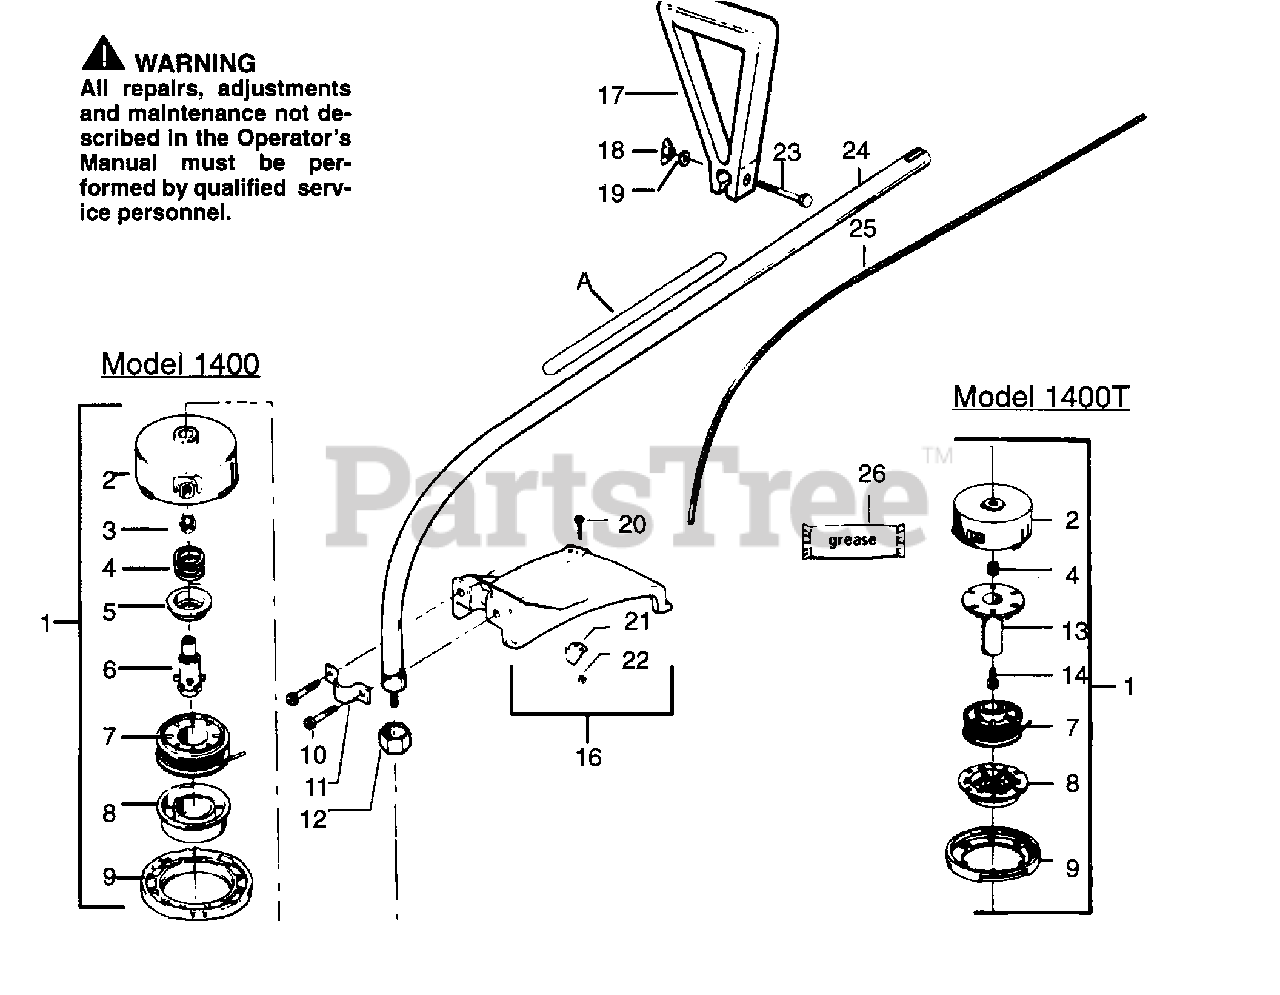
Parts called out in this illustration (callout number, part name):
1	Cutting Head Ass'y.-See Service Ref. 3
2	Model 1400 G.TRIMMER
2	Model 1400T
3	Line Saver-Model 1400 G.TRIMMER Only
4	Model 1400 G.TRIMMER
4	Model 1400T
5	Spring Adaptor-Model 1400 G.TRIMMEROnly
6	Drive Gear-Model 1400 G.TRIMMER Only
7	Model 1400 G.TRIMMER
7	Model 1400T
8	Model 1400 G.TRIMMER
8	Model 1400T
9	Model 1400 G.TRIMMER
9	Model 1400T
10	Model 1400T
12	Dust Cup
13	Spool Post
16	Model 1400T
17	Assist Handle
18	Wing Nut
21	Model 1400 G.TRIMMER
21	Model 1400T
22	Nut
24	Drive Shaft Ass'y.
25	Drive Shaft
26	Shaft Lubrication
A	Safety Label Decal
